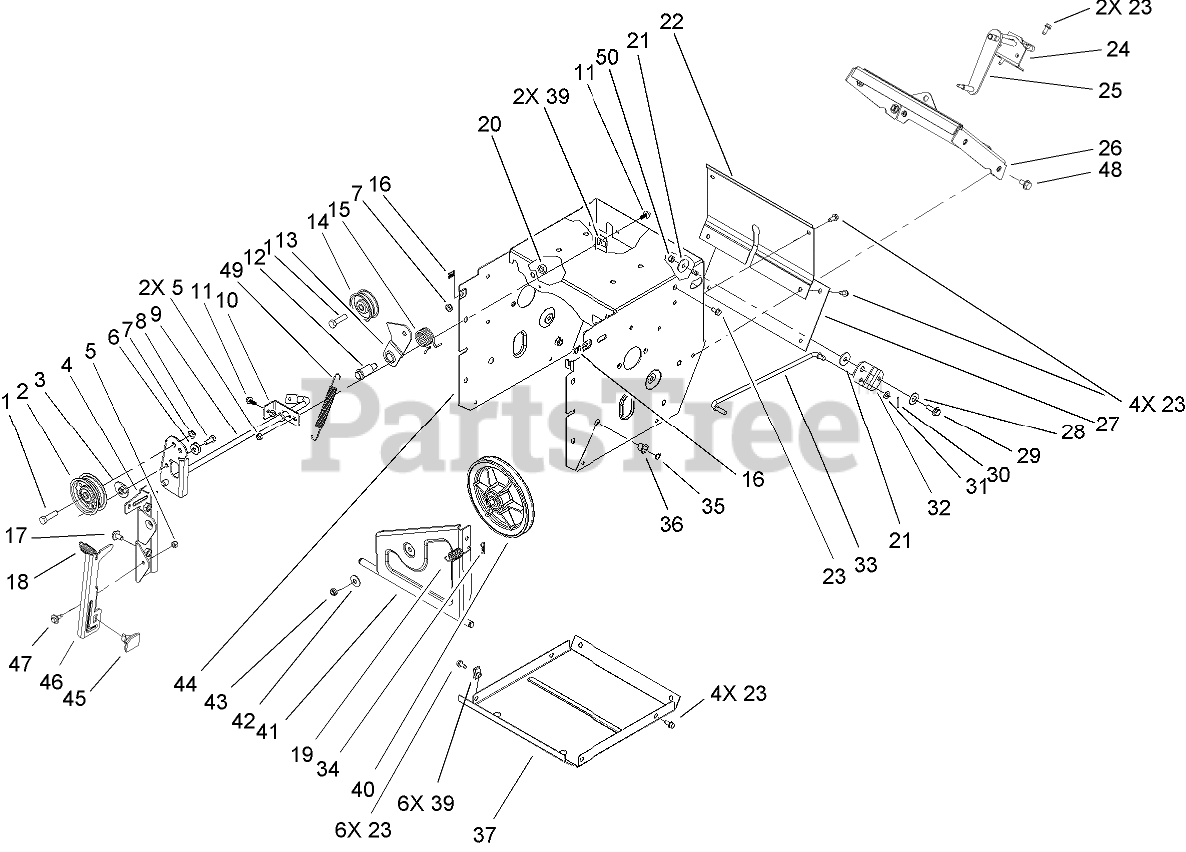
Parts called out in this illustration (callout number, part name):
1	SCREW-HH
2	PULLEY-IDLER
4	BRACKET-IDLER, IMPELLER
5	NUT-LOCK, NI
6	WASHER-BELLEVILLE
7	NUT-LOCK, NI
8	SCREW-HH
9	IMPELLER CLUTCH ASM
10	BRACKET-REAR, CLUTCH
11	SCREW-HHF
12	BOLT-SHOULDER
13	ARM-IDLER, TRACTION
14	PULLEY-IDLER
15	SPRING-TORSION
16	NUT-SPEED, U-TYPE
17	SCREW-HHF
18	SPRING-EXTENSION
19	SPRING-EXTENSION
20	NUT-LOCK, NI
21	WASHER-PIVOT
22	COVER-UPPER
23	SCREW-HWH
24	BRACKET-ROD, SHIFT
25	LEVER-CONTROL, TRACTION
26	SHIFT PLATE ASM
27	COVER-LOWER
28	WASHER
29	SCREW-SHOULDER
30	PIN-COTTER
31	WASHER-PLAIN
32	BELLCRANK-DRIVE
33	LINK-CONTROL, SPEED
34	PIN-COTTER
35	RING-RETAINING
36	BUSHING-NYLINER
37	PAN-BOTTOM
40	PULLEY-TRACTION
41	PULLEY PIVOT ASM
42	WASHER-BELLEVILLE
43	NUT-HEX
44	TRACTION FRAME ASM
45	PAD-BRAKE
46	ARM-BRAKE
47	SCREW-SHOULDER
48	SCREW-HWHTF
49	SPRING-EXTENSION
50	NUT-LOCK, NI
